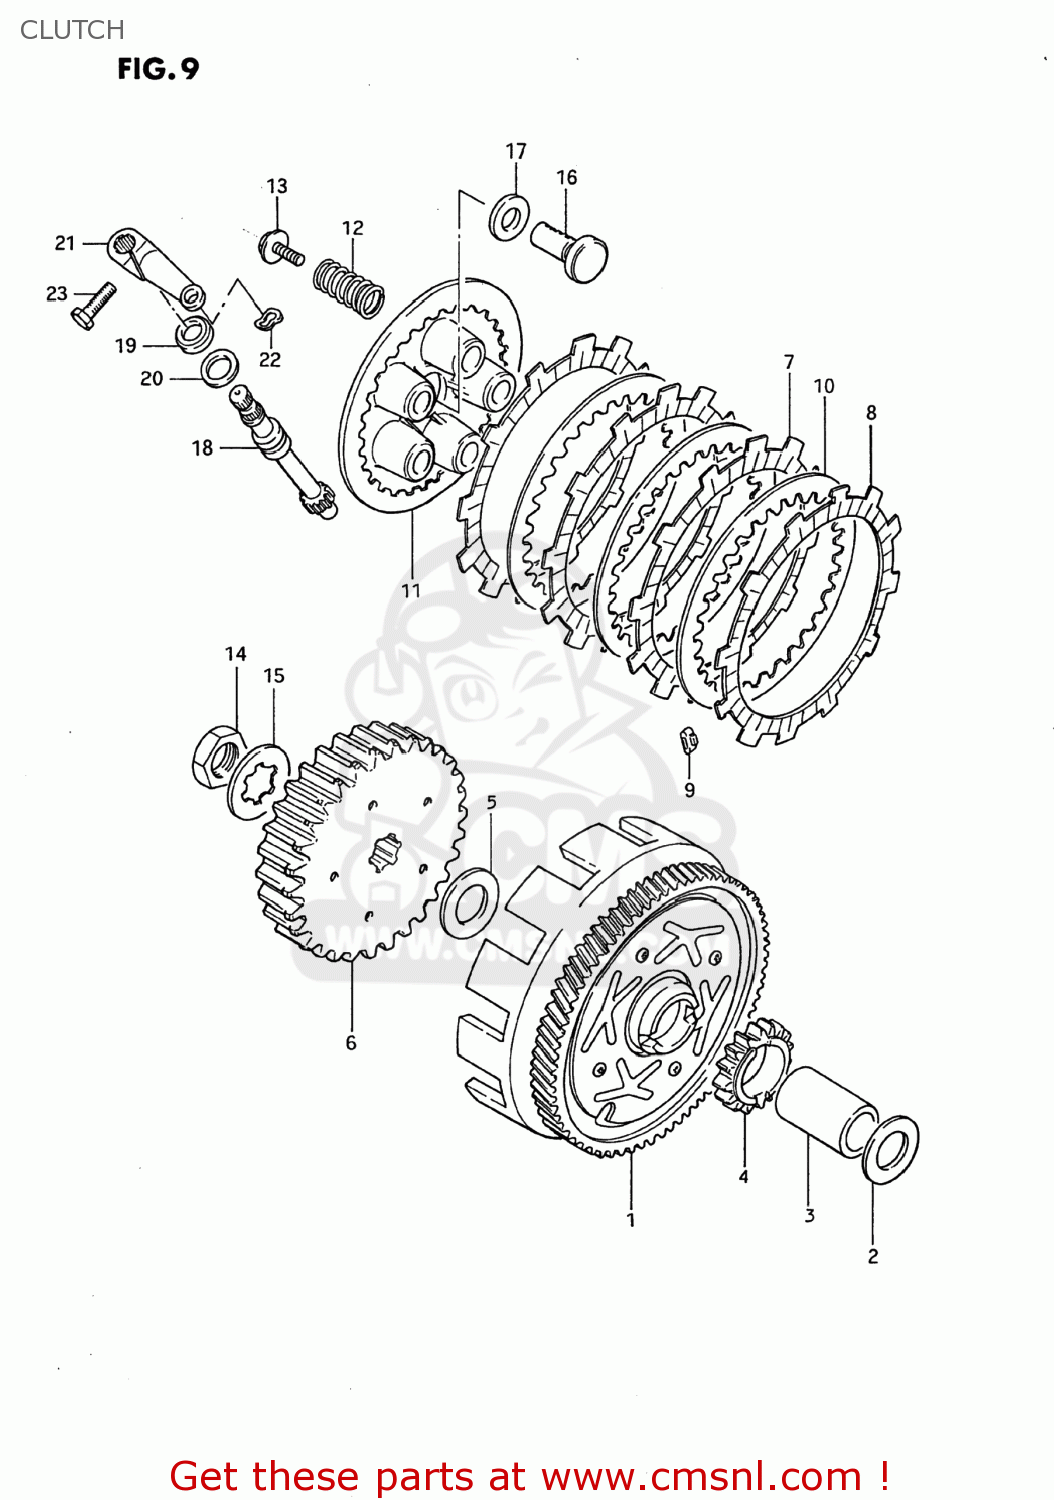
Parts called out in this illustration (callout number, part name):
1	GEAR ASSY,PRI DRIVEN(NT:73)
2	WASHER,THRUST
3	SPACER
4	GEAR,KICK STARTER DRIVE
5	WASHER
6	HUB,CLUTCH SLEEVE
7	PLATE,CLUTCH DRIVE (NAS)
8	PLATE,CLUTCH DRIVE (NAS)
9	DAMPER
10	PLATE,CLUTCH DRIVEN (NAS)
11	DISC,CLUTCH PRESSURE
12	SPRING
13	BOLT 5X16
14	NUT
15	WASHER,LOCK
16	RACK,CLUTCH RELEASE
17	BEARING(10X22X2.8)
18	PINION,CLUTCH RELEASE
19	SEAL,OIL(10X17X5)
20	WASHER
21	ARM,CLUTCH RELEASE
22	WASHER
23	BOLT
